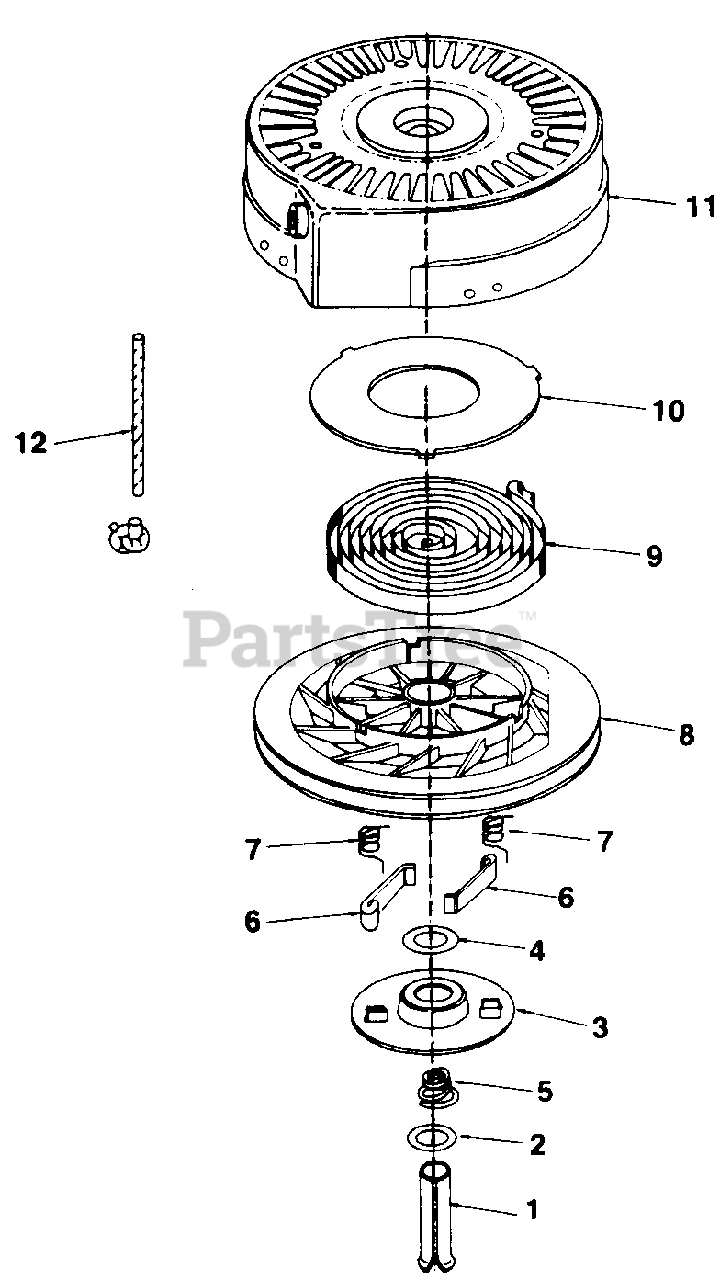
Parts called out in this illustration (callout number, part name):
1	Pin, Spring
5	Spring, Brake
6	Dog, Starter
7	Spring, Dog
8	Pulley
9	Spring, Rewind
10	Cover, Spring
11	Housing Ass'y., Starter
12	Rope, Starter
